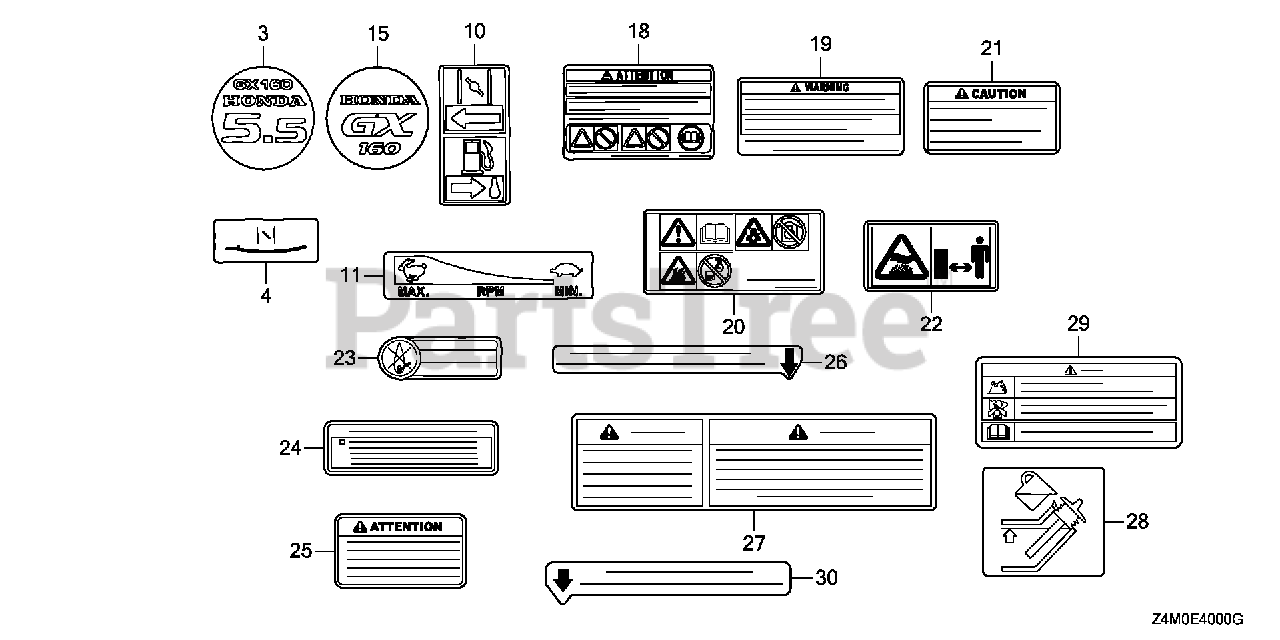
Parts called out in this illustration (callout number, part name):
18	MARK, OPERATOR CAUTION (Honda Code 8018962). (FRENCH)(MADE IN THAILAND)
19	MARK, OPERATOR CAUTION (FRENCH)(MADE IN THAI)
20	MARK, OPERATOR CAUTION (PICTOGRAPH)
21	MARK, EX. CAUTION (FRENCH)
22	MARK, EX. CAUTION (PICTOGRAPH)
